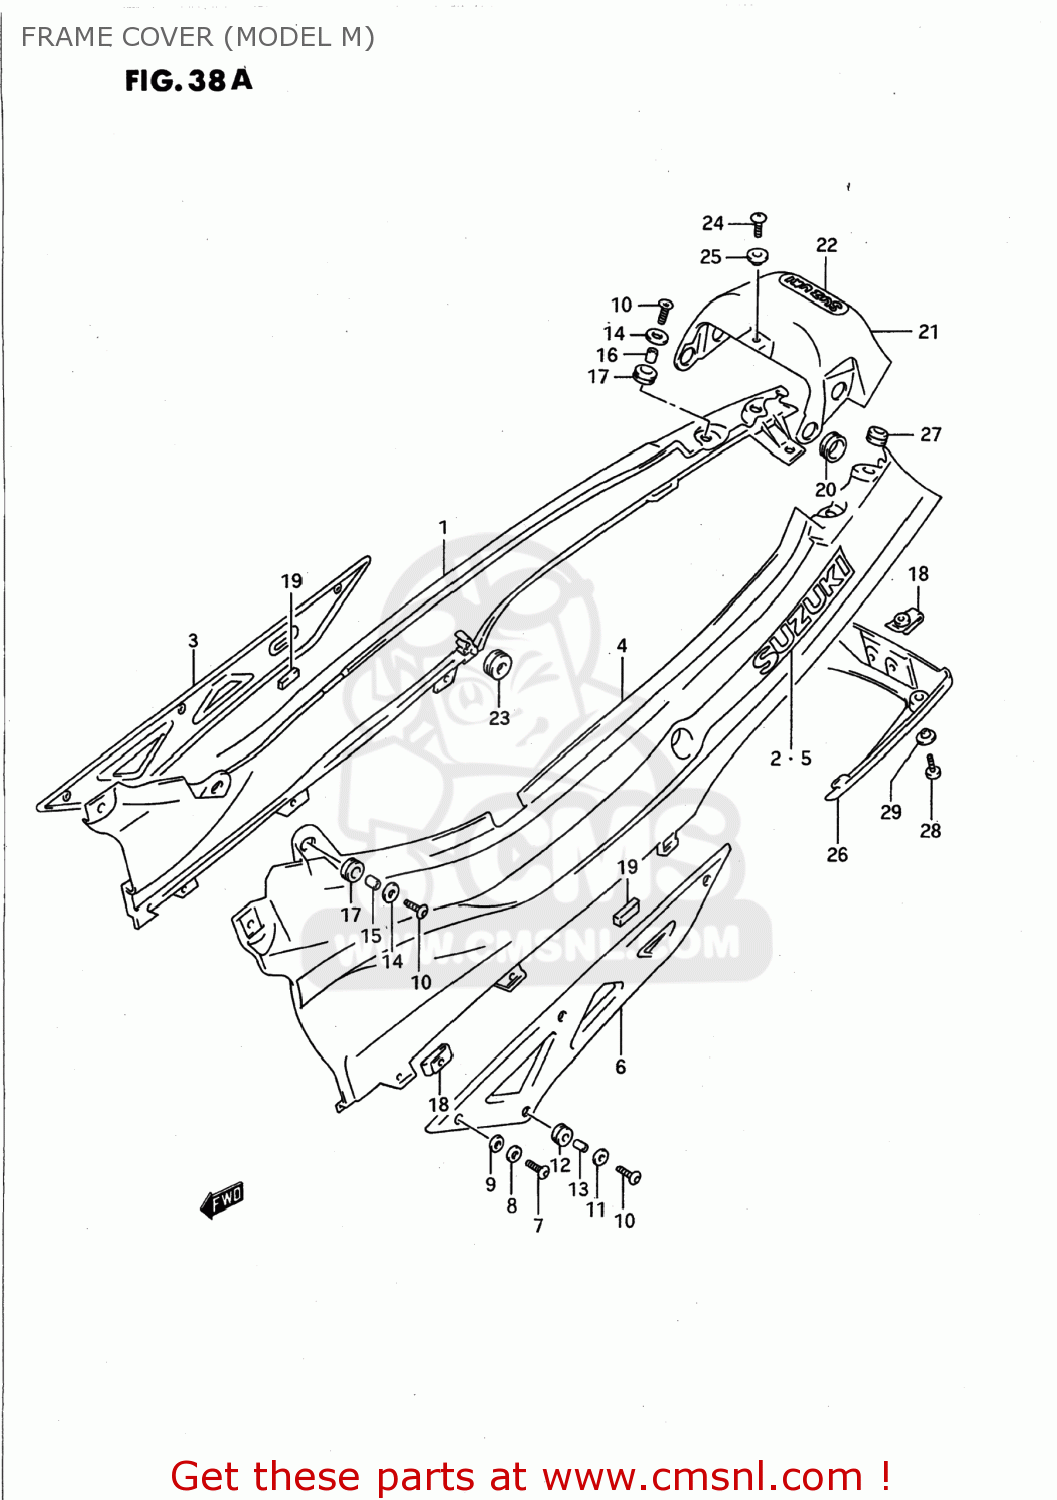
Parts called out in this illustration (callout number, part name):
1	COVER,FRAME,RIGHT
2	TAPE,FRAME COVER
3	COVER,FRAME LWR,R
4	COVER,FRAME,LEFT
5	TAPE,FRAME COVER
6	COVER,FRAME LWR,L
7	SCREW(6X16)
8	WASHER (6.7X16X1.8)
9	WASHER (5.5X16X1)
10	SCREW(6X16)
11	WASHER(6.5X22X1.6)
12	CUSHION
13	SPACER(6.2X8.3X6.1)
14	WASHER
15	SPACER (6.1X9X9)
16	SPACER(6.1X9X7.5)
17	CUSHION
18	PLATE,FRAME COVER
19	CUSHION,FRAME COVER LWR
20	GROMMET
21	COVER,FRAME,CENTER
22	EMBLEM
23	CUSHION
24	SCREW 6X10
25	WASHER
26	COVER,FRAME RR
27	CUSHION
28	SCREW
29	WASHER
